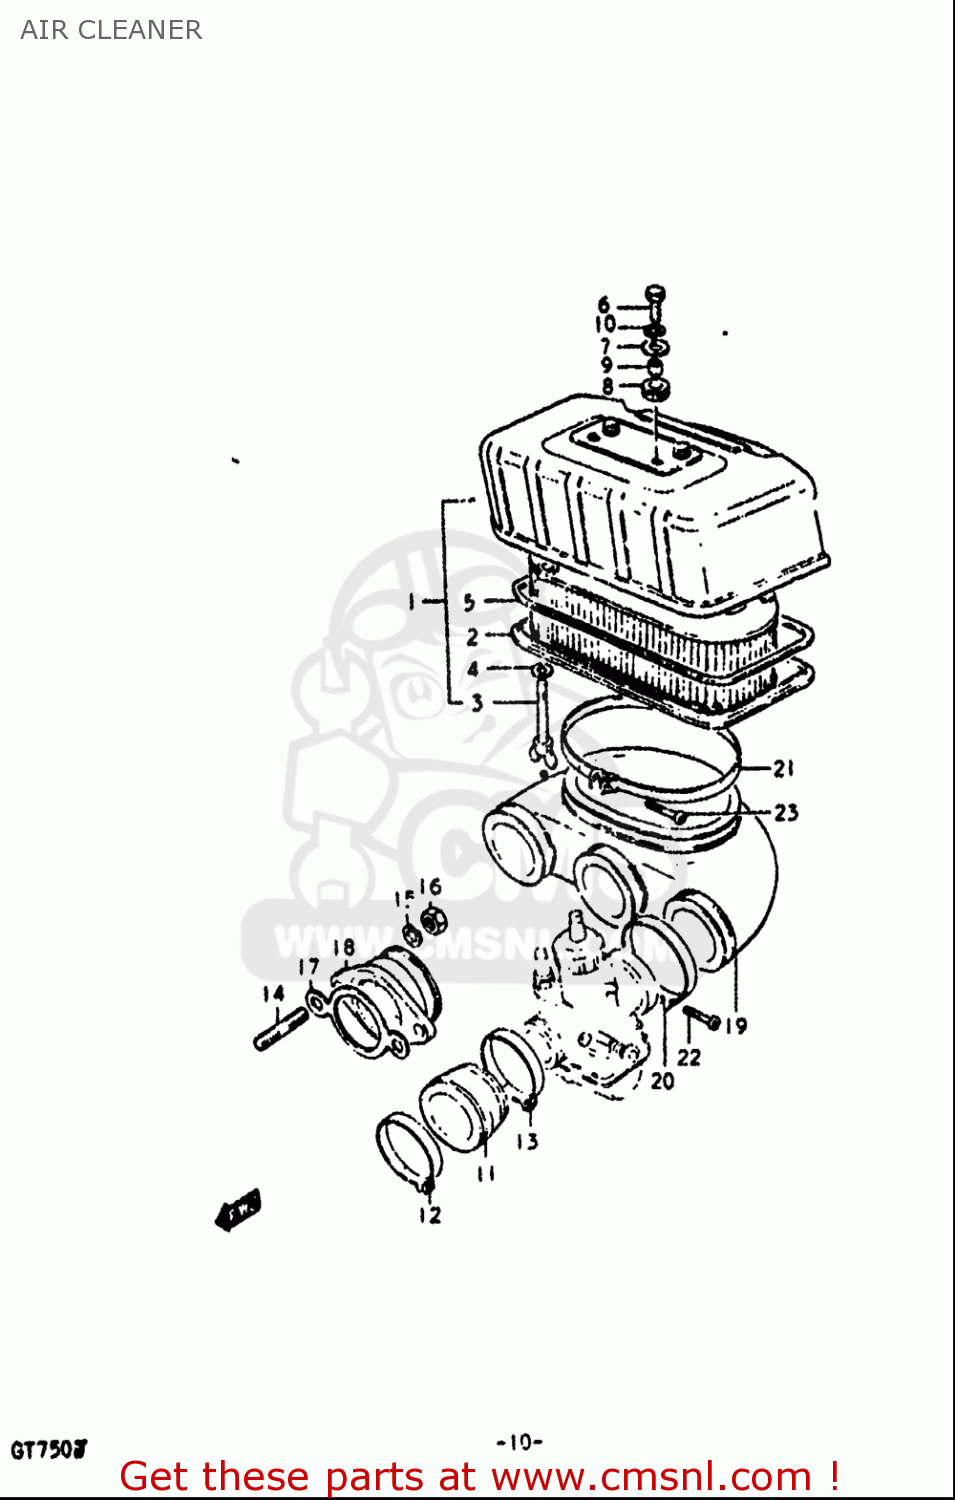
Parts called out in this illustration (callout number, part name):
2	FILTER ASSY
4	WASHER
6	BOLT
7	WASHER(6.5X20X1.2)
8	CUSHION
9	SPACER,6.5X9X7
10	WASHER,LOCK
11	PIPE,INTAKE
12	CLAMP
13	CLAMP
14	STUD BOLT
15	WASHER,LOCK
16	NUT
17	GASKET,CARBURETOR (NAS)
18	PIPE,INTAKE
20	CLAMP
22	SCREW
